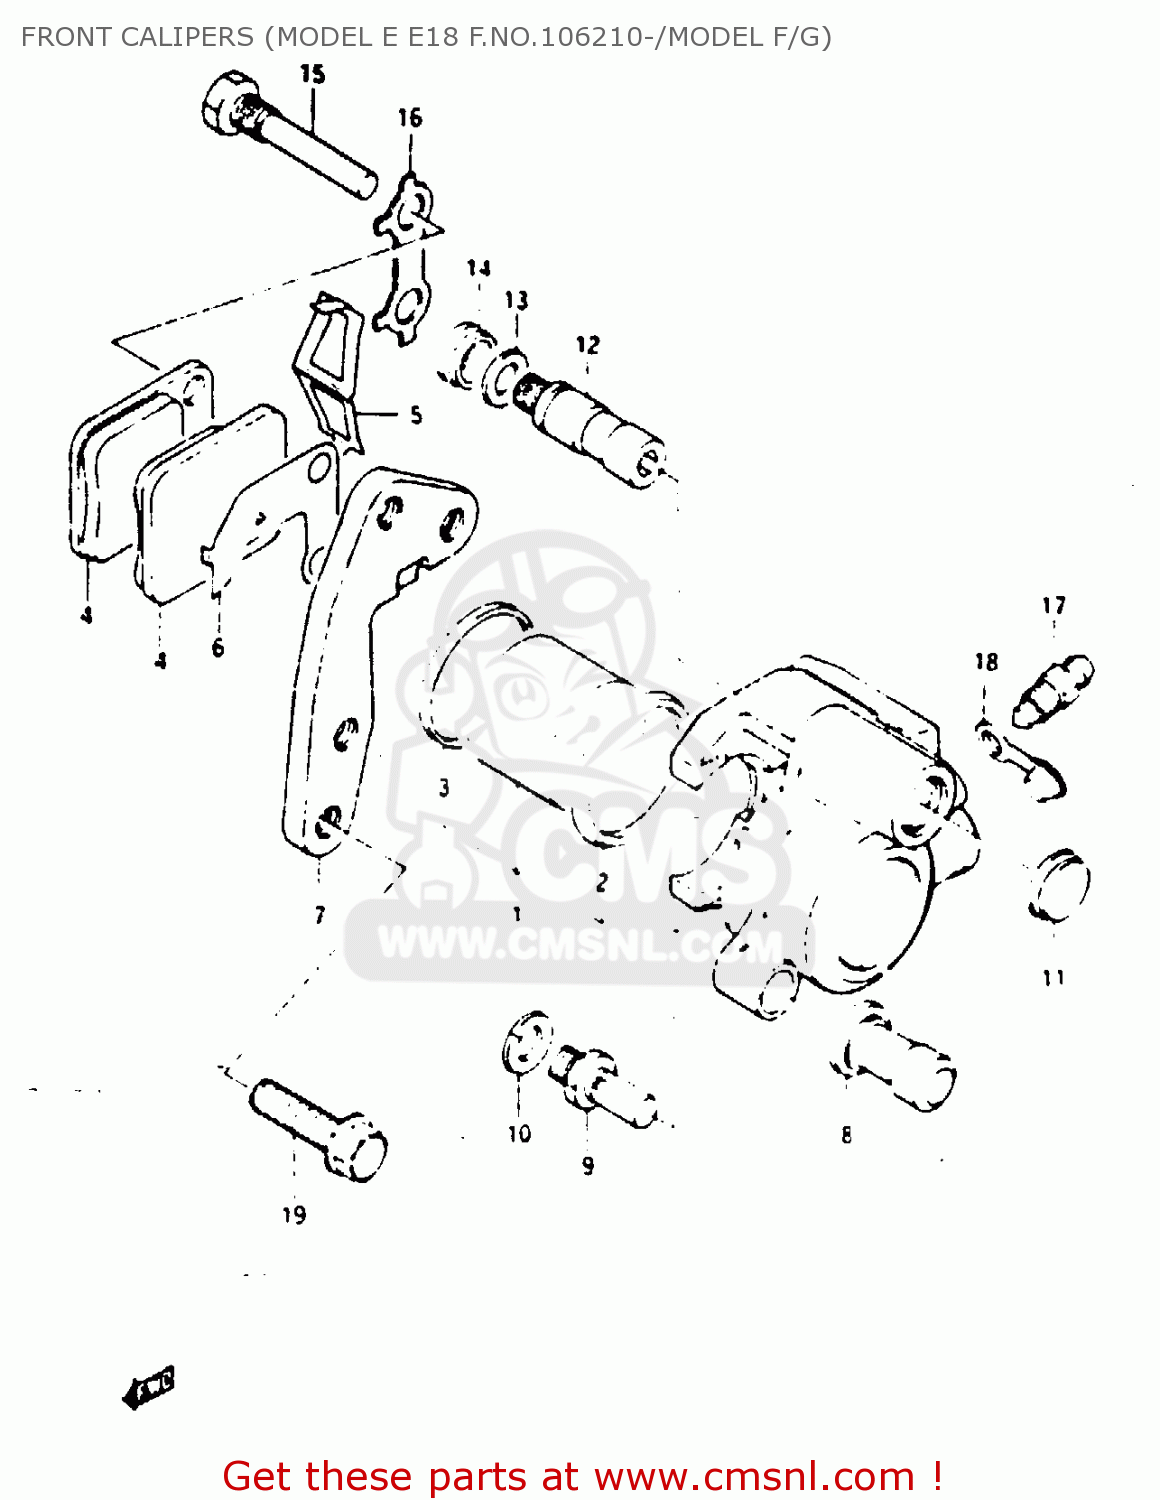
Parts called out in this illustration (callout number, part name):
1	PISTON SET,CALIPERS
2	SEAL,PISTON
3	BOOT,PISTON
4	PAD
5	SPRING,PAD
6	SHIM
7	BRACKET
8	BOOT
9	BOLT,PIN
10	WASHER,WAVE
11	DUST SEAL
12	PIN,SLIDE
13	SPRING,FRICTION
14	BOOT,PIN
15	PIN,HANGER
16	WASHER
17	BLEEDER
18	CAP,BLEEDER
19	BOLT 8X30
